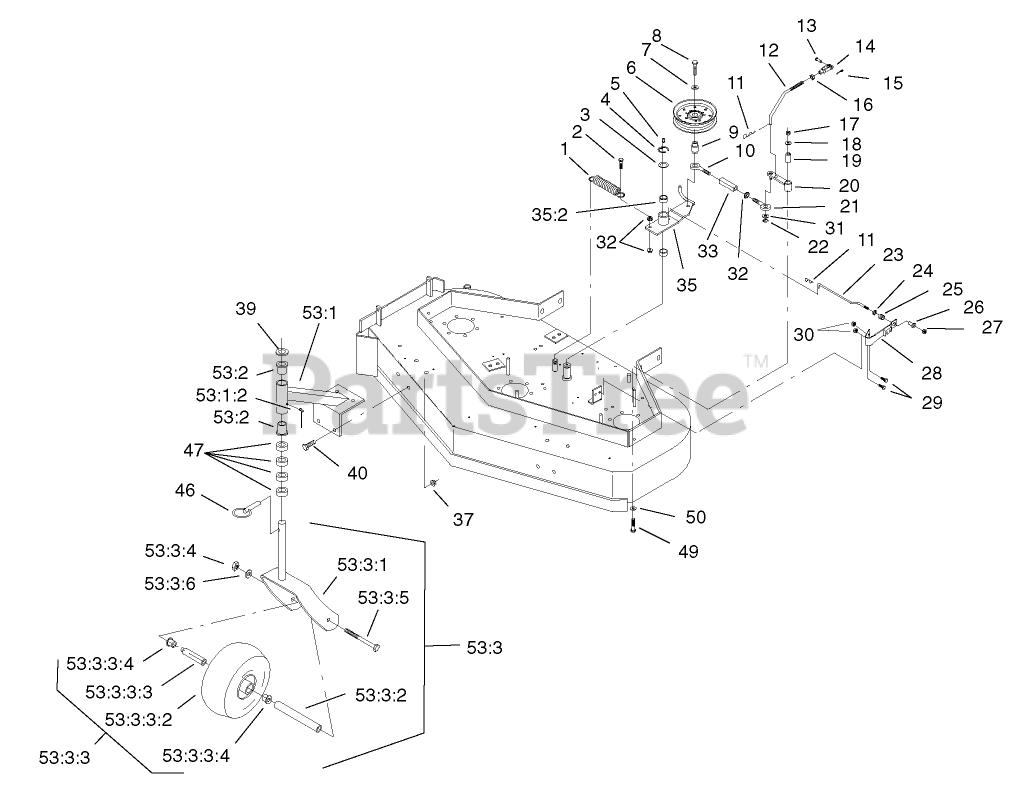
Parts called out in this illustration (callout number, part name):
1	SPRING-EXTENSION
2	SCREW-HH
3	WASHER-SPINDLE
4	RING-RETAINING, EXT
5	FITTING-GREASE
6	PULLEY-IDLER
7	WASHER-BELLEVILLE
8	SCREW-HH
9	BUSHING-ENGAGEMENT
10	EYEBOLT-THREAD, LH
11	PIN-COTTER
12	ARM-LINKAGE, ASSIST
13	PIN-CLEVIS
14	YOKE-ADJUSTABLE
15	PIN-COTTER
16	NUT-HEX
17	NUT-LOCK, NI
18	WASHER-FLAT
19	TUBE-PIVOT
20	ARM-ASSIST
21	EYEBOLT-THREAD, RH
22	RING-RETAINING, EXT
23	ROD-BRAKE
24	RING-PUSH ON
25	SPRING-COMPRESSION
26	SPACER-FLANGED
27	NUT-LOCK, NI
28	PAD AND SPRING ASM
29	SCREW-HH
30	NUT-LOCK, NI
31	WASHER-PLAIN
32	NUT-HF
33	BODY-TURNBUCKLE
35	ASM,IDLER ARM/BUSHINGS
35:2	SLEEVE-BEARING
37	NUT-HHF, WHIZ
39	WASHER-FLAT
40	SCREW-HH
47	SPACER-CASTER
49	SCREW-HH
50	WASHER-SPRING
53	Castor Wheel And Mount ASM
53:1	SUPPORT-CASTER
53:1:2	FITTING-GREASE
53:2	BEARING-FLANGED
53:3	CASTER/WHEEL ASM
53:3:1	FORK
53:3:2	SPACER
53:3:3	WHEEL AND TIRE ASM
53:3:3:3	BEARING
53:3:3:4	BUSHING
53:3:4	NUT-HH
53:3:5	SCREW-HH
53:3:6	WASHER-LOCK
